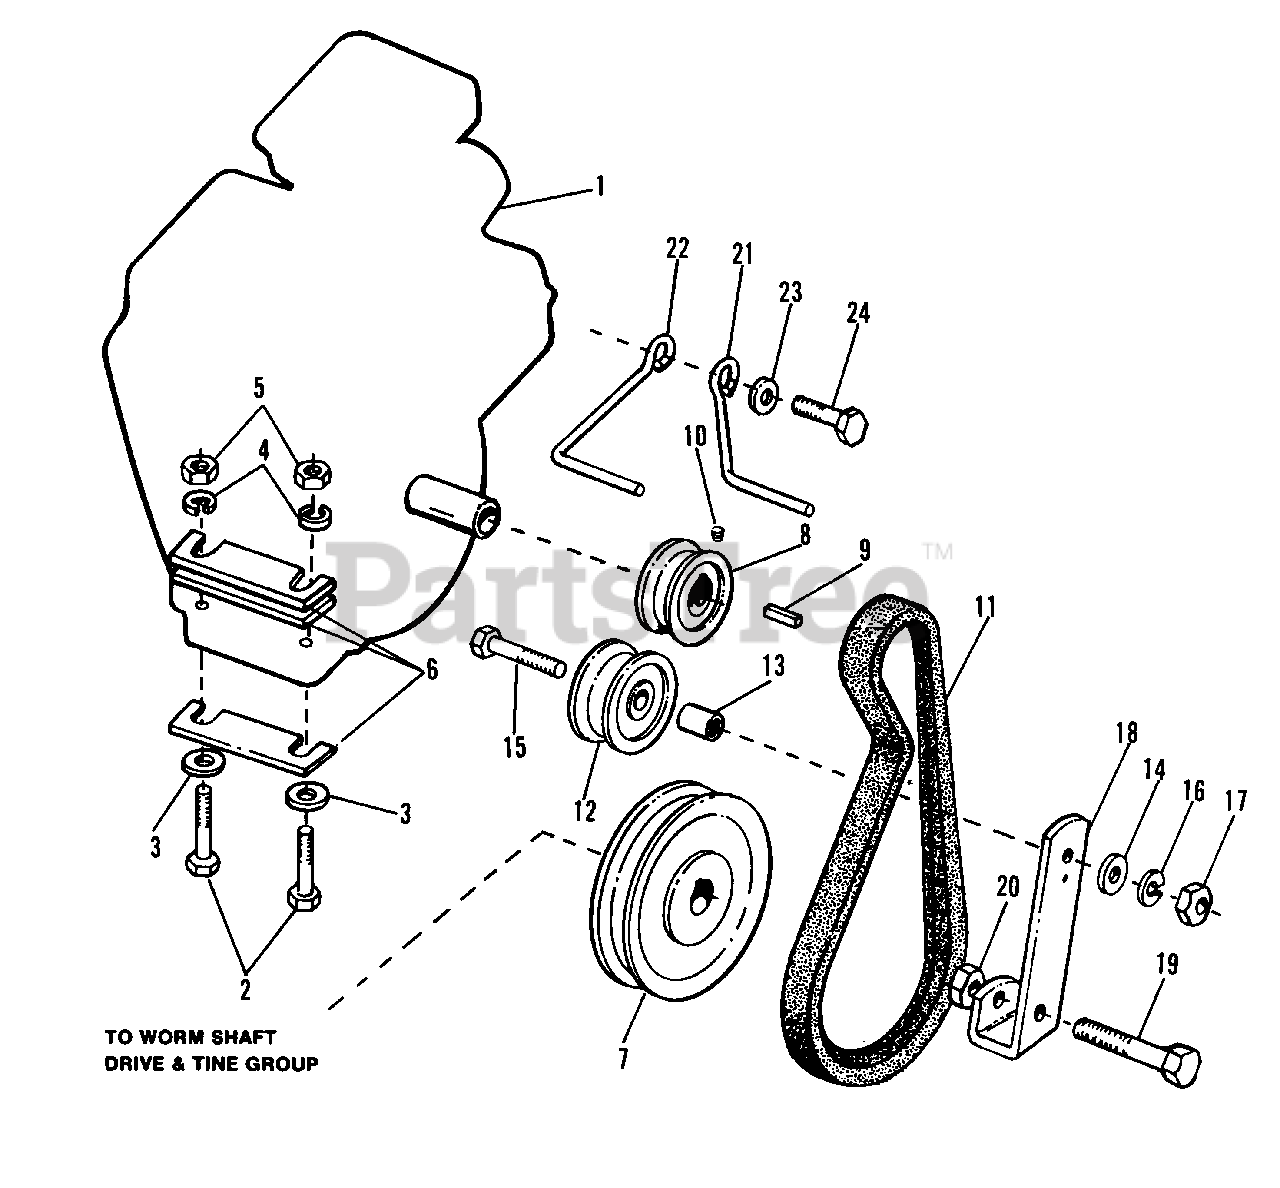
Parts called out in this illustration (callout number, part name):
2	CAPSCREW, Hex, 5/16-18 x 2
3	WASHER, Flat, 5/16
4	LOCKWASHER, 5/16
5	NUT, Hex, 5/16-18
7	PULLEY, Driven
8	PULLEY, Engine
9	KEY, Square
10	SETSCREW, Cup
12	PULLEY, Idler
14	WASHER, Flat, 5/16
15	CAPSCREW, Hex, 3/8-16 x 1-3/4
16	LOCKWASHER, 3/8
17	NUT, Hex, 3/8
18	LEVER, Idler Pulley
19	BOLT, Pivot
20	LOCKNUT, Hex, 5/16
22	STOP, Belt
23	LOCKWASHER, 1/2
24	CAPSCREW, Hex, 1/2-20 x 1
